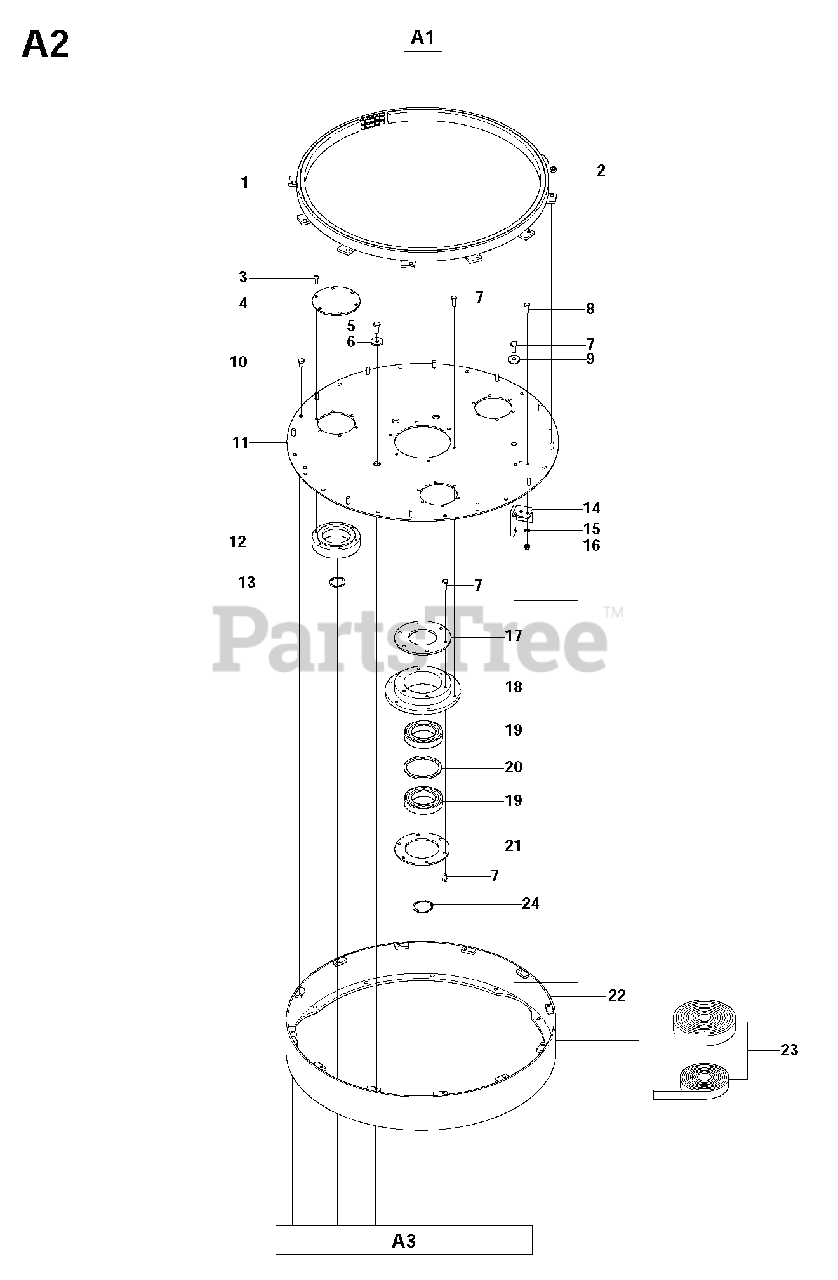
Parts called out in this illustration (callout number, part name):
2	HEXAGON LOCKING NUT
15	WASHER
16	HEXAGON LOCKING NUT
